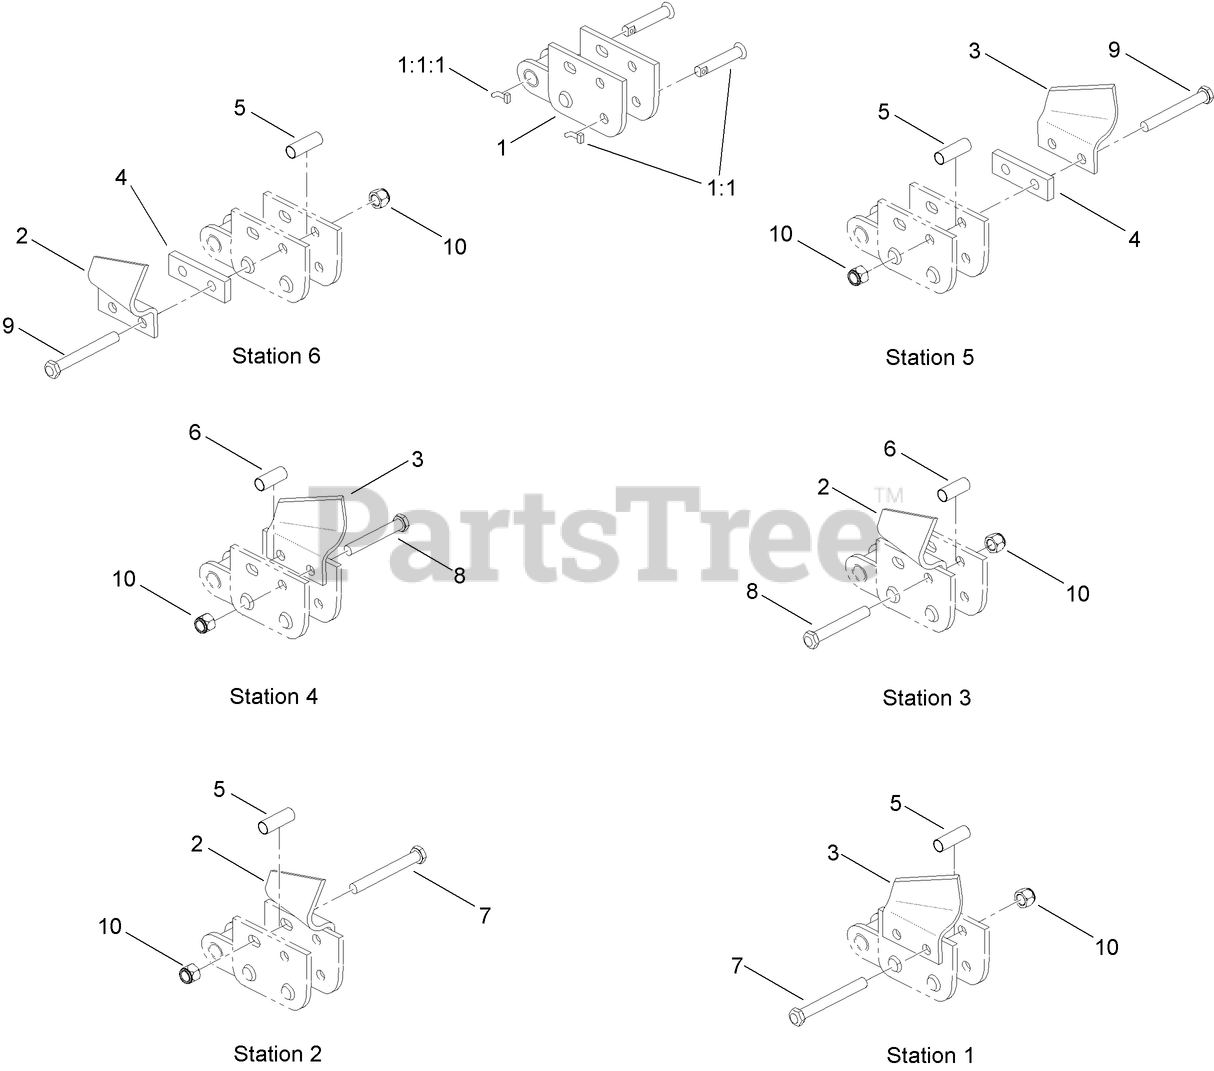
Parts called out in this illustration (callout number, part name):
1	CHAIN REPAIR LINK ASM
1:1	NOTCHED PIN AND KEEPER ASM
1:1:1	PIN-KEEPER
2	CUTTER-CUP, RH
3	CUTTER-CUP, LH
4	SPACER-FLAT
5	SPACER-TUBE, OUTSIDE MOUNT
6	SPACER-TUBE, INSIDE CUP
7	BOLT-HH
8	BOLT-HH
9	BOLT-HH
10	NUT-LOCK
